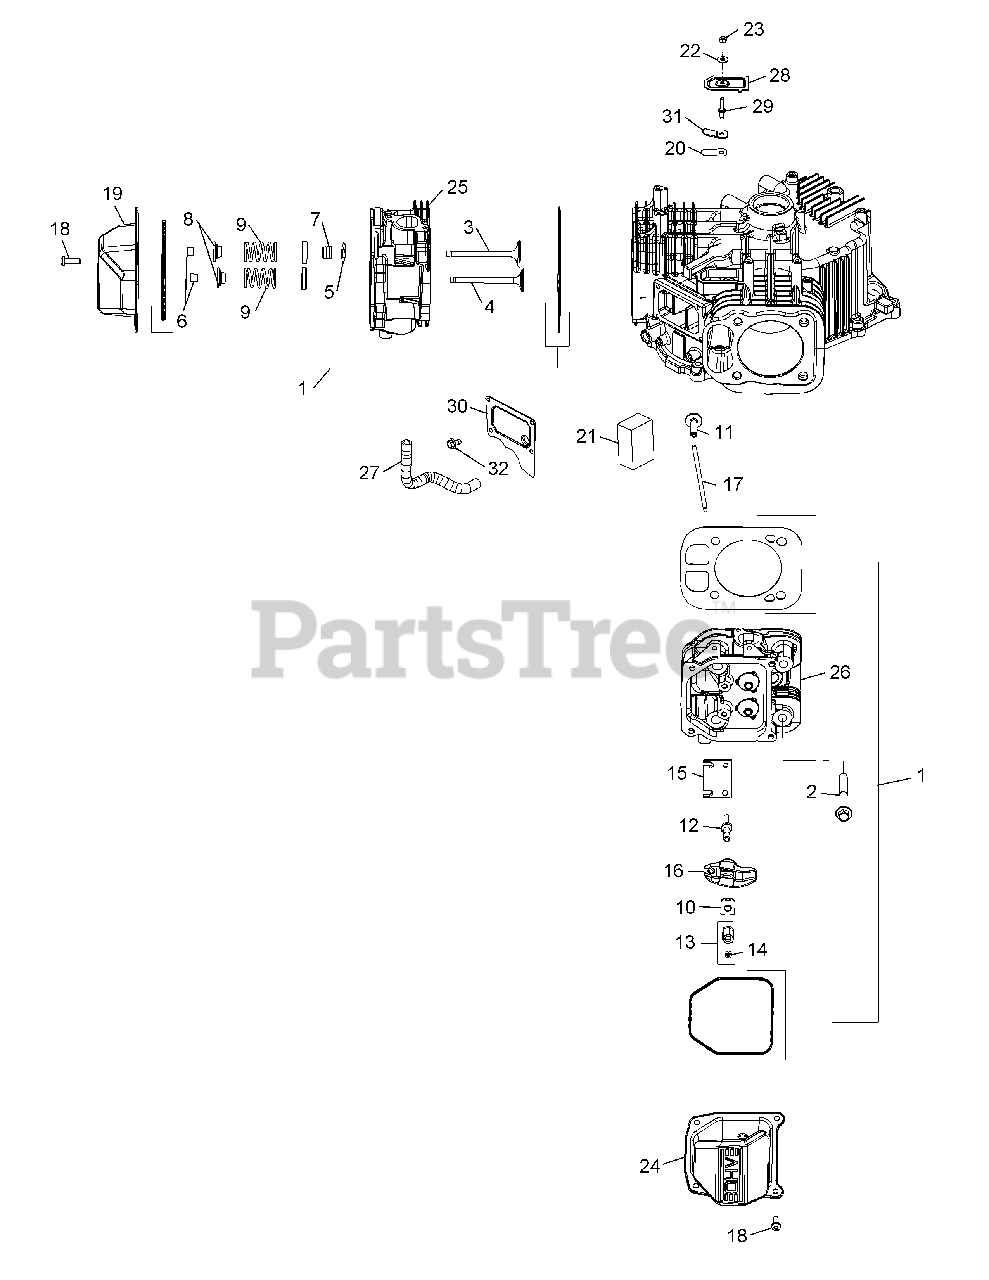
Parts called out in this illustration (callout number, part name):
1	Cylinder Head Gasket Kit
2	Flange Screw, M10 x 1.5 x 90
4	Exhaust Valve
5	Spacer (.010")
6	Retainer Kit
7	Valve Band Seal
8	Valve Spring Cap
9	Valve Spring
10	Rocker Arm Pivot
13	Hex Nut Assembly (Inc. #14)
18	Pan Head Screw
20	Breather Reed
21	Breather Filter
22	Sealing Washer
23	Lock Nut, M5 x 8
24	Rocker Cover
25	Cylinder Head Assembly Kit, #1
26	Cylinder Head Assembly Kit, #2
27	Breather Hose
28	Breather Cover
30	Breather Media Cover
31	Reed Retainer
32	Thread Forming Screw
